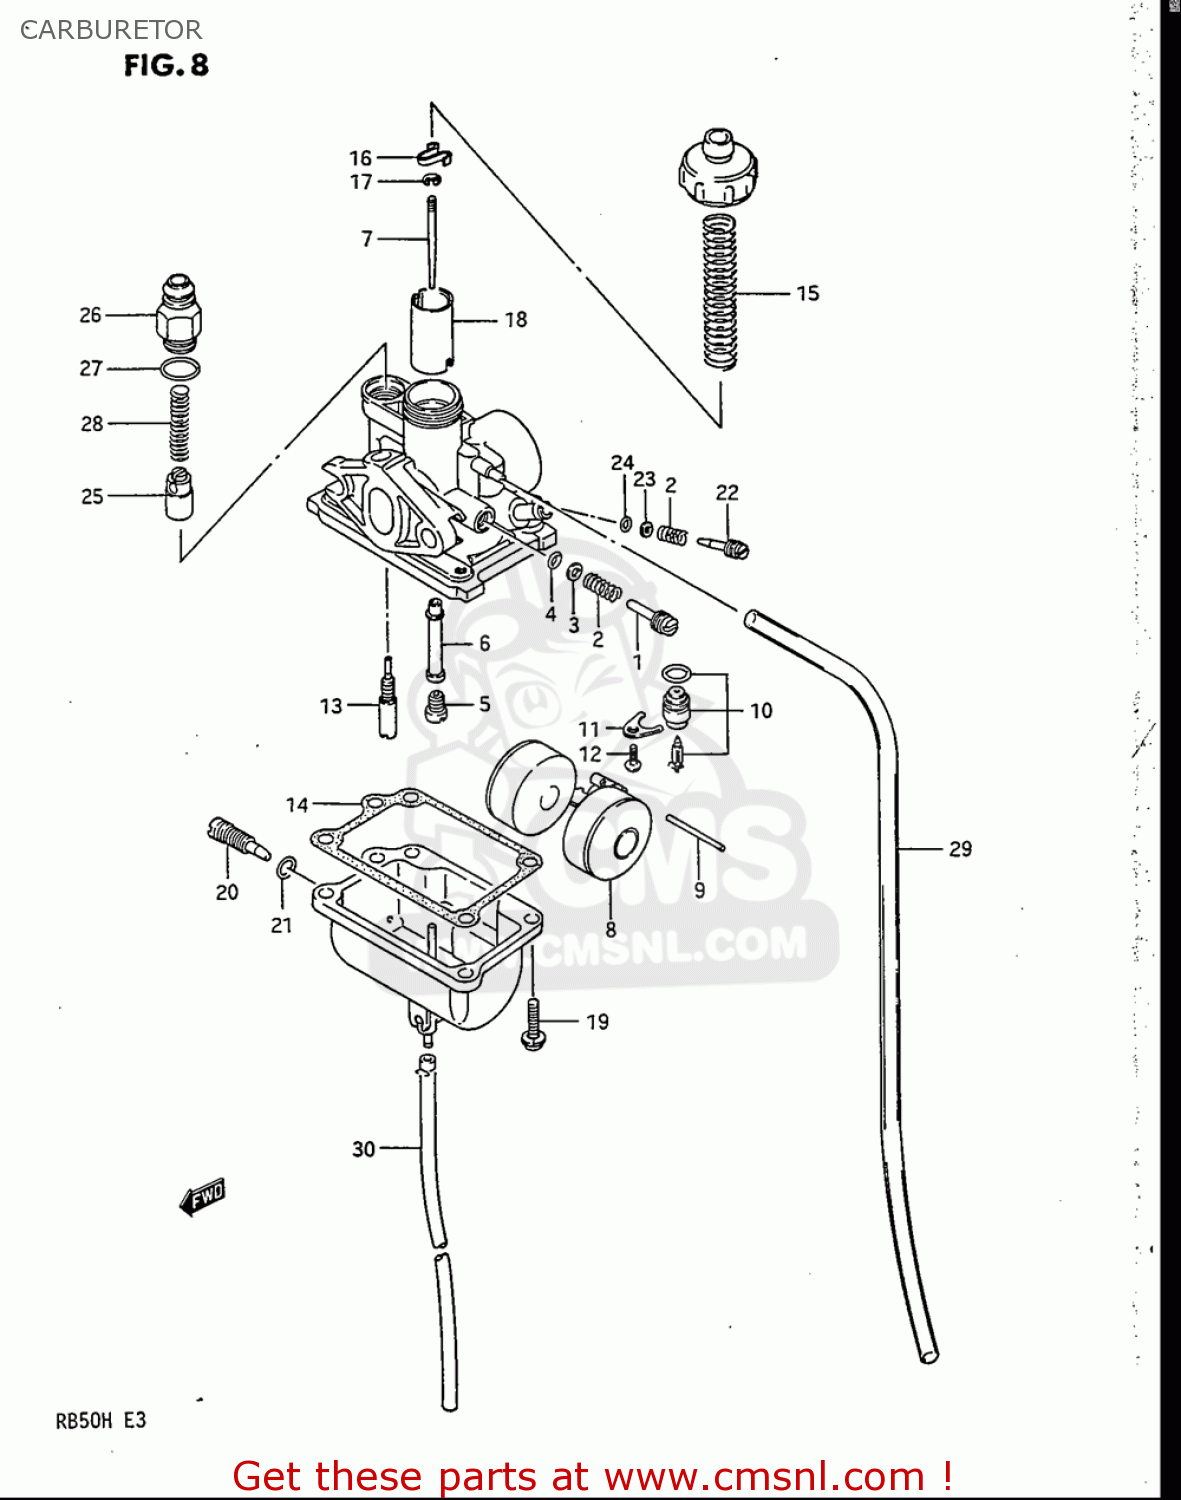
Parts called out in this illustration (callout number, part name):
1	SCREW,THROTTLE STOP
2	SPRING
3	WASHER
4	O RING
5	JET,MAIN(80)
8	FLOAT
9	PIN,FLOAT
10	VALVE ASSY,NEEDLE
11	PLATE,NEEDLE VALVE FITING
12	SCREW
13	JET,PILOT(15)
14	GASKET (NAS)
15	SPRING,THROTTLE VALVE
16	SEAT,THROTTLE VALVE SPRING
17	CLIP,NEEDLE
18	VALVE,THROTTLE
19	SCREW
20	PLUG,DRAIN
21	O RING
22	SCREW,PILOT AIR
23	WASHER
24	O RING,PILOT AIR SCREW
25	PLUNGER,STARTER
26	CAP,STARTER
27	O RING
28	SPRING
29	HOSE(3X5X600)
